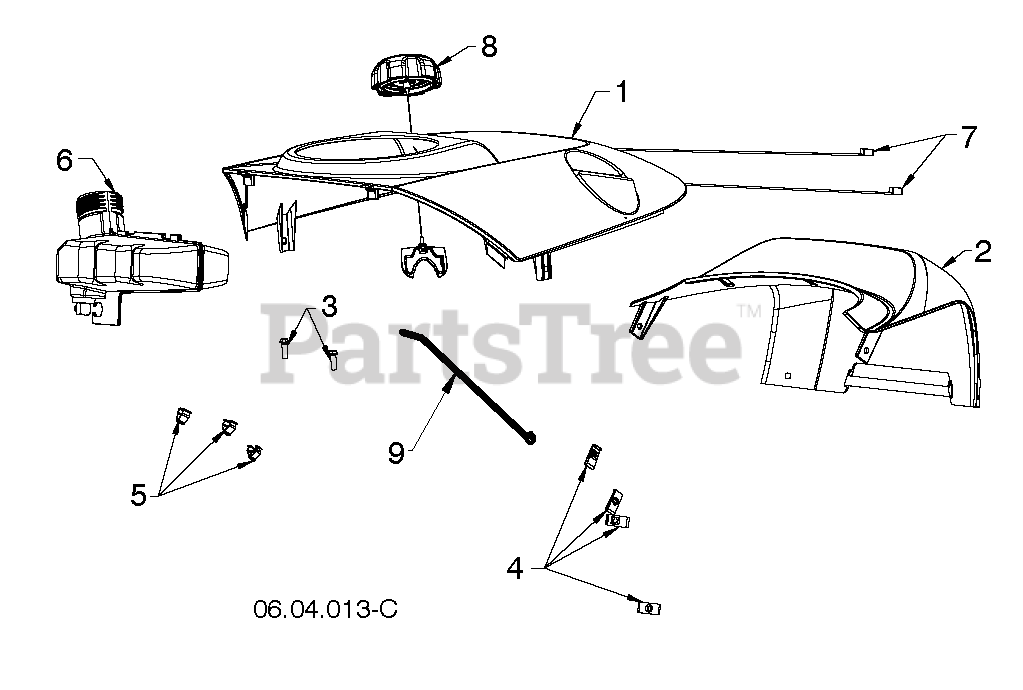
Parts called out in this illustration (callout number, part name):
2	TOP.REAR.COVER
3	SCREW.HX.13X.750
6	TANK.GAS.12.SINGLE.STAGE.SNOW
7	TIE.CABLE.24.5X.29.NYLON.WHITE
8	CAP.2.25'.VENTED.RATCHET.EPA
